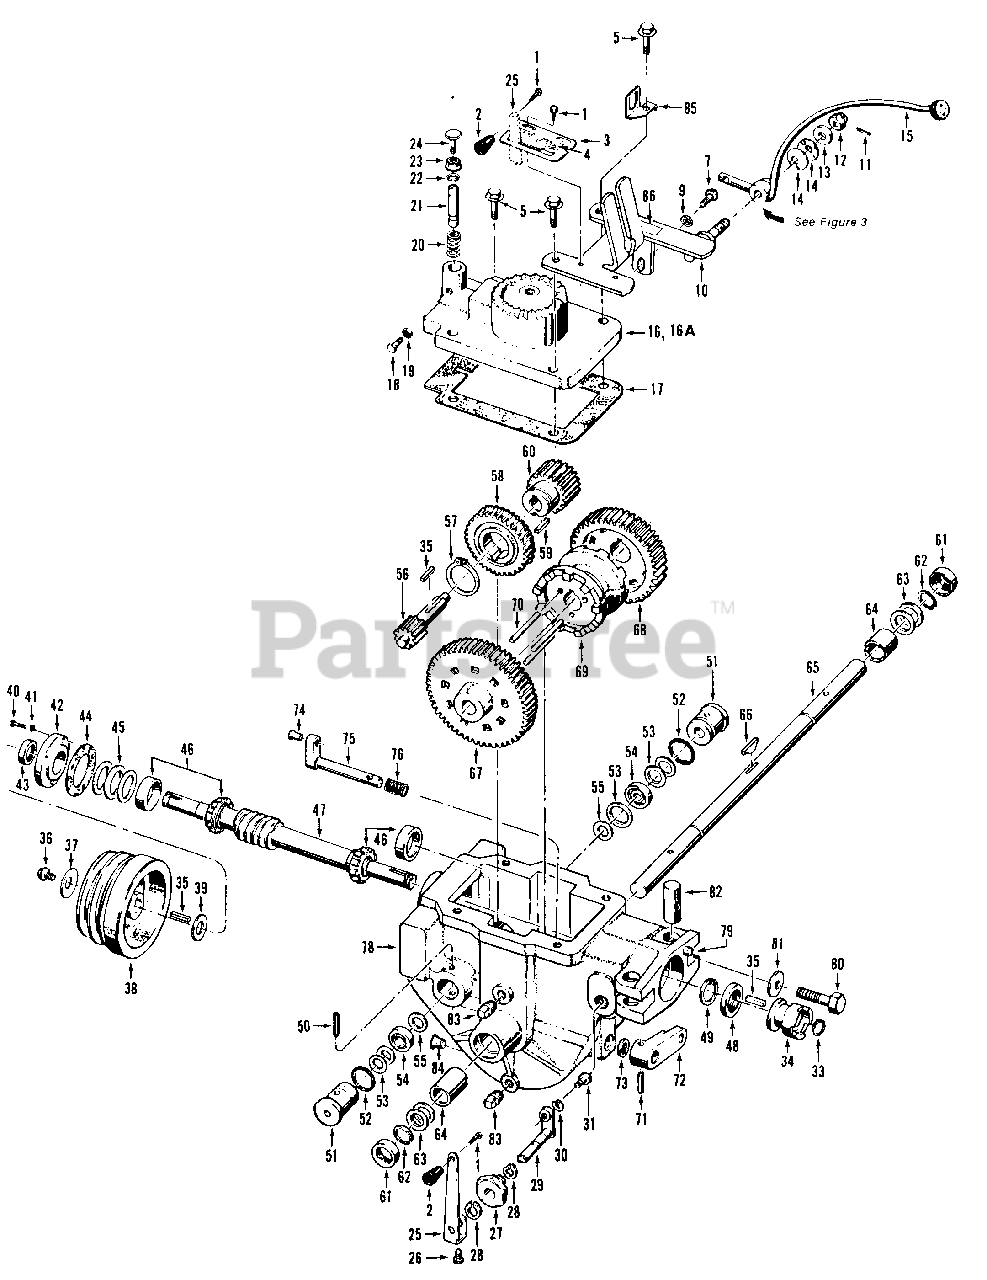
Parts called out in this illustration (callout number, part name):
1	Bolt-hex hd., #10-32 x 3/8", self-locking flange
2	Knob-tines/PTO clutch lever, tapered, plastic
3	Detent Plate-tines/PTO clutch lever
4	Decal-operating instructions, detent plate
5	Bolt-flanged hex hd., 3/8-16 x 1-1/2"
7	Bolt-flanged hex hd., 5/16-18 x 3/4", Grade 5
9	Washer-flat, 5/16", S.A.E
10	Bracket-shift levers
11	Pin-spring, 1/8"
12	Nut-castle (slotted), 1/2"-20
13	Washer-shoulder, 1/2"
14	Washer-disc spring
15	Lever-wheel speed shift
16	Cover-power unit transmission
16A	Cover-power unit transmission
17	Gasket-transmission cover
18	Bolt-hex hd., 5/16-18 x 1", Grade 5,
19	Nut-hex, 5/16"-18
20	Spring-neutral plunger
21	Plunger-neutral
22	Clip Ring-retains neutral plunger
23	Nut-hex, flange locknut, 3/8"-16
24	Bolt-hex hd., 3/8-16 x 1-1/2", threaded full length
25	Lever-eccentric, Tines/PTO clutch.
26	Bolt-hex hd., 1/4-20 x 1/2"
27	Bushing-tines/PTO clutch lever eccentric shaft
28	Retaining Ring (snap ring), external
29	Eccentric-shaft, tines/PTO clutch lever
30	Lockwasher-hi-collar, 1/4"
31	Screw-socket hd., 1/4-20 x 3/8"
33	Retaining Ring-external
34	Dog Clutch-power unit
35	Key-3/16 sq. x 1"
36	Bolt-hex hd., 5/16-24 x 3/4", self-locking flange, Grade 5
37	Washer-disc spring
38	Pulley-transmission drive, cast iron
39	Washer-flat, hardened shoulder 1-1/4"
40	Bolt-hex hd., 1/4-20 x 3/4", front bearing cap
42	Cap-front bearing
43	Seal-oil, front bearing cap
44	Gasket-front bearing cap
45	Shim-front bearing cap, .010" thick
46	Bearing & Cup-tapered cone roller bearing with cup (race).
47	Shaft-main drive, power unit.
48	Seal-oil, drive shaft, rear
49	Retaining Ring-(snap ring), internal
50	Pin-roll (spirol), 1/4 x 2"
51	Plug-retaining, pinion bearing
52	O-Ring-retaining plug
53	Shim-retaining plug, 1-1/64" inner dia, .033" thick
54	Bearing-ball, pinion shaft
55	Washer-pinion shaft
56	Stem Pinion-slow, speed gear & shaft
57	Ring-retaining, external
58	Worm Gear-bronze, wheel drive
59	Key-3/16" x 5/8"
60	Gear-fast speed pinion
61	Seal-oil, wheel shaft
62	Retaining ring-external
63	Shim-wheel shaft, 1-1/64" inner dia, 062" thick
64	Bushing-bronze, wheel shaft bearing
65	Shaft-wheel, 15-5/8"
66	Key-Hi Pro, 1/4" x 1-3/4"
67	Gear-slow speed, wheel drive
68	Gear-fast speed, wheel drive
69	Dog Clutch-wheel drive
70	Pin-clutch guide, 1/4" diameter
71	Pin-roll, 3/16" x 1-1/4" (spiral)
72	Lever-eccentric, wheel speed shifting
73	Seal-oil, eccentric shaft
74	Pin-eccentric shaft, wheel speed shifting
75	Eccentric Shaft-wheel speed shifting
76	Spring-eccentric shaft
78	Housing-power unit transmission
79	Pin-alignment
80	Bolt-hex hd., 1/2-13 x 2" Grade 5.
81	Washer-disc spring
82	Post-with threaded hole for Ref. No. 80
83	Plug-pipe, 1/4"
84	Plug-red plastic, thread protector.
85	Clip-forward interlock system plug connector
86	Decal-forward interlock wire harness
